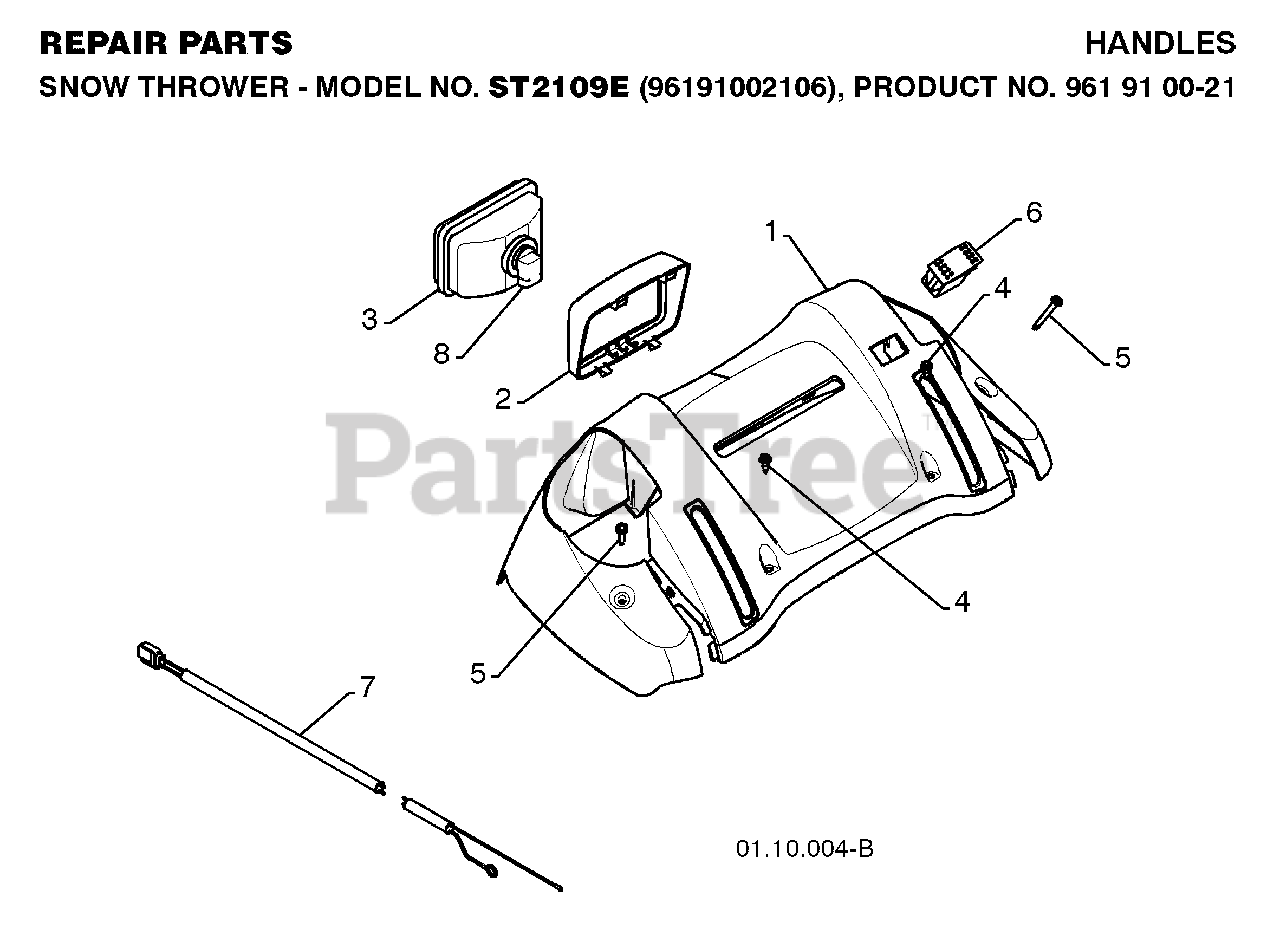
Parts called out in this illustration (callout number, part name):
2	BEZEL.HEADLIGHT.BLACK
3	HEADLIGHT, HALOGEN
4	SCREW, HEX HEAD, TAPPING
5	SCREW, HEX HD TAPPING #10-24 1
6	SWITCH.HEATED.GRIP
7	HARNESS.WIRE.LIGHT/GRIP.SNOW
8	BULB.HEADLIGHT.HALOGEN.
